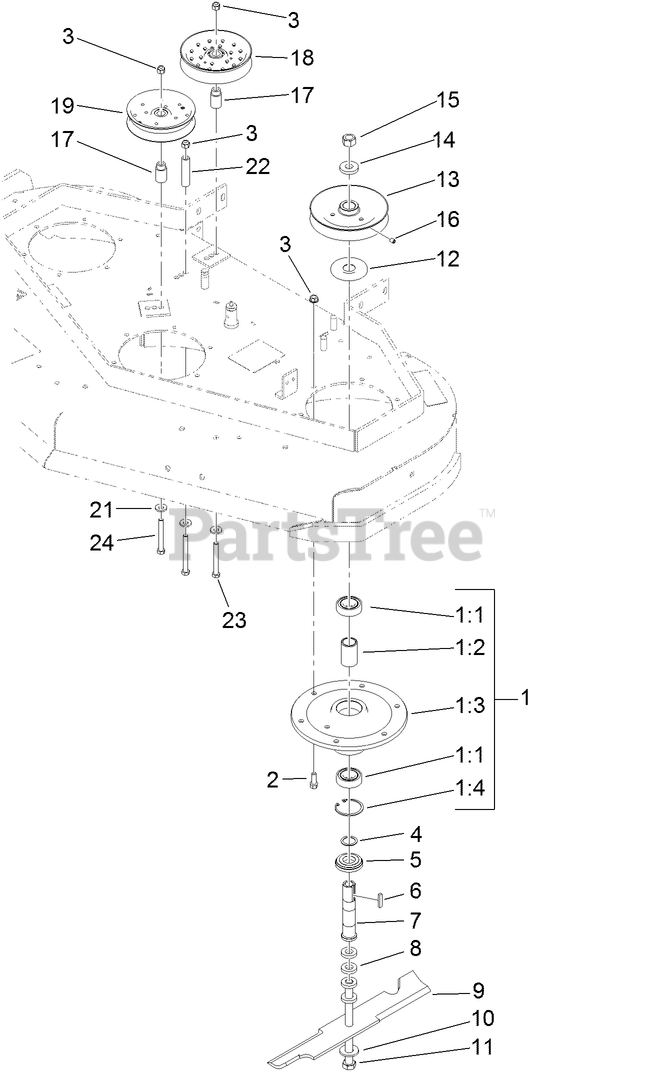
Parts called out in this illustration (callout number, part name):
1	SPINDLE HOUSING ASM
1:1	BEARING-BALL, 1 INCH
1:2	SPACER-BEARING
1:3	HOUSING-SPINDLE
1:4	RING-SNAP
2	SCREW-HWH
3	NUT-HF, NI
4	WASHER-SPACER
5	SPACER-GUARD, BOTTOM
7	TUBE-SPINDLE, SHORT
8	SPACER
9	BLADE-16.5 INCH (HIGH FLOW)
10	WASHER-SPRING
11	SCREW-CAP, HH
12	Guard-Bearing, Top
13	SHEAVE
14	WASHER-RETAINER, SHEAVE
15	NUT-HEX
16	SETSCREW
17	BUSHING-IDLER
18	IDLER-PULLEY, FLAT
19	PULLEY-IDLER
21	WASHER-BELLEVILLE
22	SPACER
23	SCREW-HH
24	SCREW-HH
